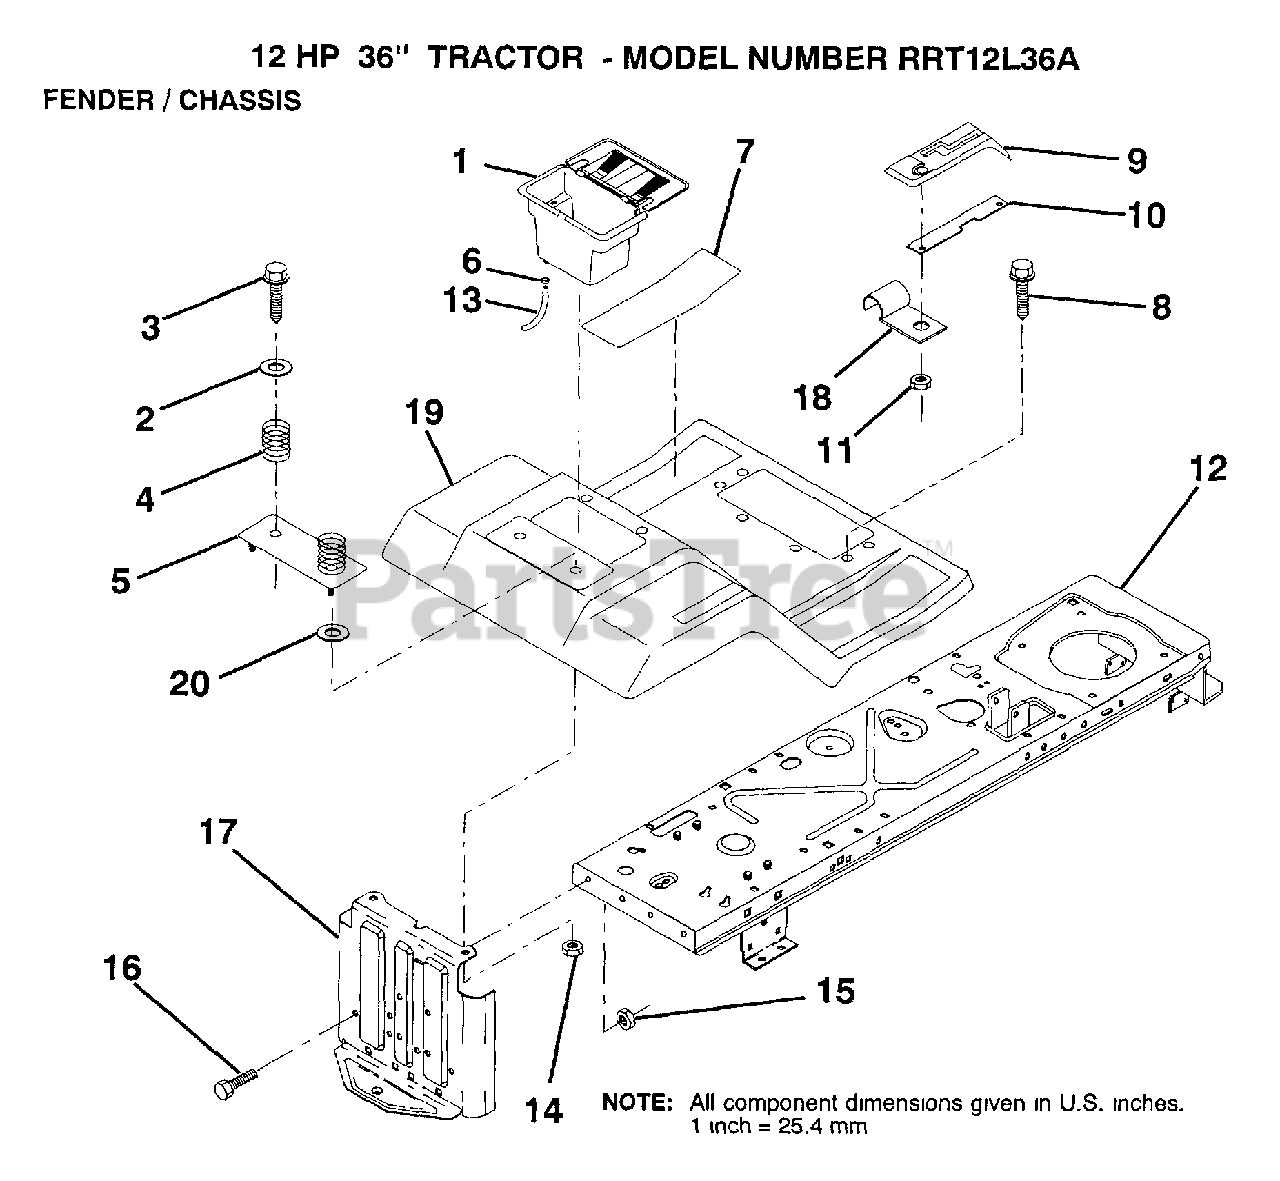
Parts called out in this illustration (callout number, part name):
2	WASHER
3	SCREW
4	SPRING COMPRESSIO
5	BTRY FENDER PLATE
6	HOSE CLAMP T
7	PAD FOOTREST
8	SCREW
11	NUT
14	NUT
16	BOLT
17	DRAWBAR
18	"CLIP,INSULATOR"
